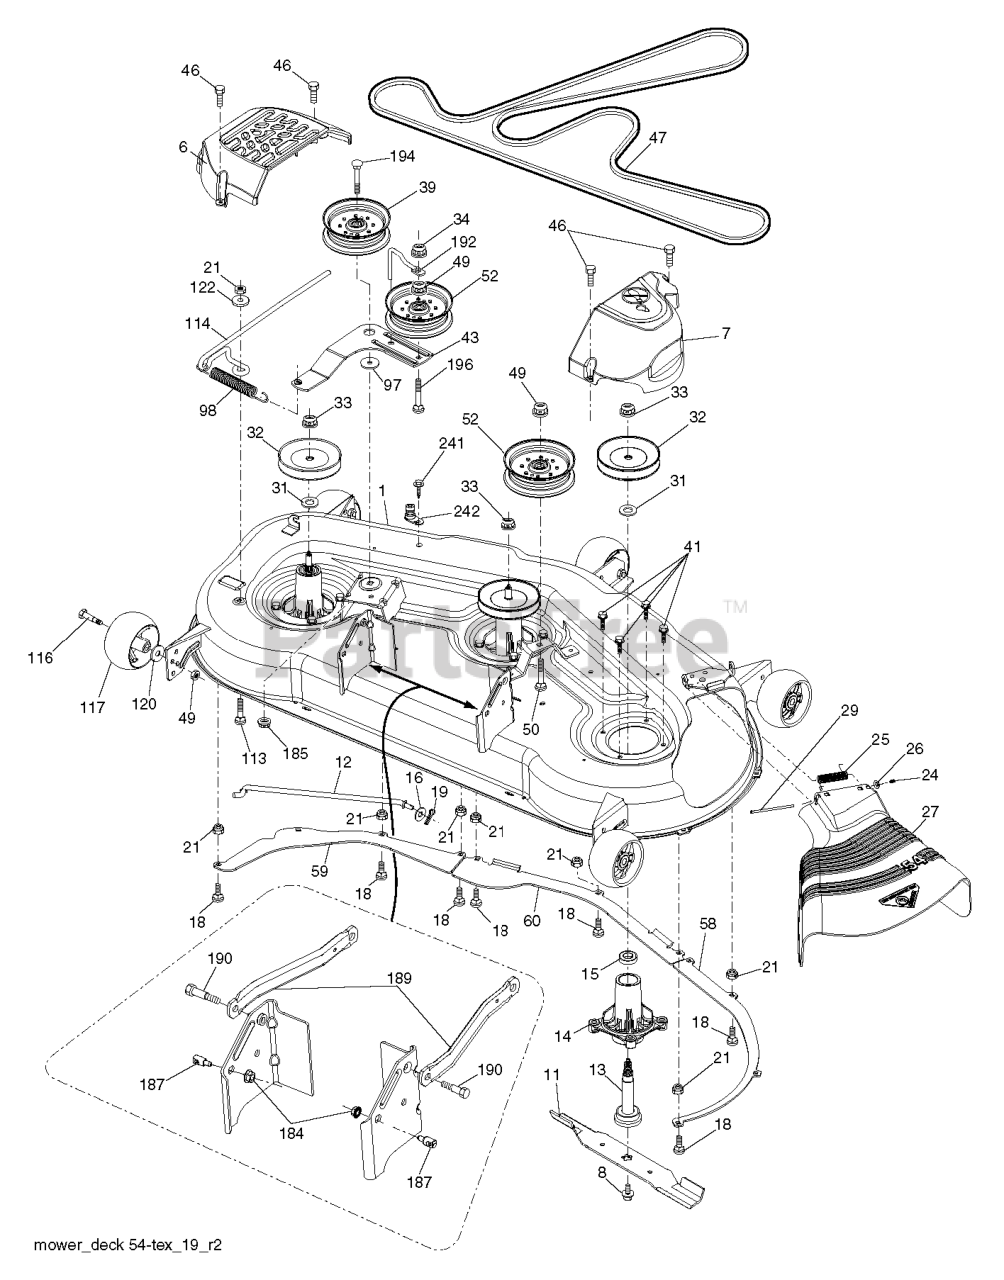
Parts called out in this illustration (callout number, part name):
1	DECK.WELDMENT.54"MS-498
6	COVER.MANDREL.LH.54"20
7	COVER.MANDREL.RH.54.20
8	BOLT.WASHER.ASM.7/16-2
11	BLADE.BAGGING.54"
12	ROD.ANTI.SWAY.48/54"K4
13	SHAFT ASM MANDREL
14	RP.HOUSING.MANDREL.4PT.
16	WASHER
18	BOLT
19	PIN.COTTER.5/16.BOW TI
21	LOCKNUT
24	CAP-SLEEVE LT
25	SPRING, TORSION
26	NUT PUSH M
27	DEFLECTOR
29	ROD.HINGE
30	SCREW, WASHER HEAD
31	WASHER.SPACER.MANDREL
32	PULLEY/MANDREL
33	NUT.FLANGE.LOCK.TOP
34	NUT SPECIAL T
39	RB PULLEY.IDLER.4.50/HUB SPEC
43	ARM.IDLER
46	SCREW.1/4-20X5/8
47	RP.BELT.DRIVE.54."2006
49	NUT LOCK FLG 3/8-16 UNC
50	BOLT
52	PULLEY.IDLER.2006
58	BAFFLE.RIGHT.54"
59	BAFFLE.LEFT.54"
60	BAFFLE CENTER 54" MOWER
98	SPRING, DECK DRIVE
113	BOLT CRT
114	ROD TENSION RELIEF
116	BOLT.SHOULDER.3/8-16X3-5/8.
117	RP WHEEL. GUAGE RALLY
120	WASHER
122	BUSHING.RELIEF.TENSION
184	NUT LOCK HEX FLANGE 5/16-18
185	NUT.LOCK.FLANGE.7/16
187	STUD.FASTNER.W/ANTI-ROTATE
189	ARM.SUSPENSION.MOWER
190	BOLT.SHOULDER
192	KEEPER.BELT.IDLER.54"T
194	BOLT.HEX.WASHER.HEAD.7/16-24X
196	BOLT
241	SCREW.TT.#10-32X.5.3/8.FLANGE
242	PORT.WASHOUT
